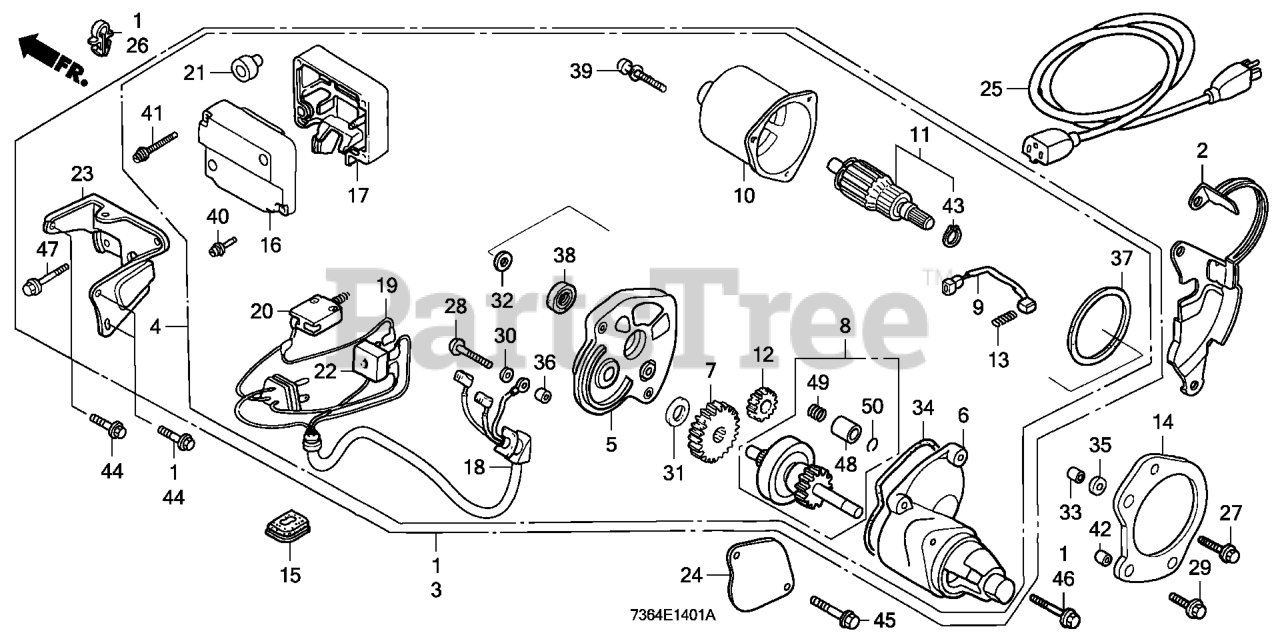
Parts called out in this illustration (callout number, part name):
2	PLATE, SIDE (A.C. SEL) Use from Engine SN 2056820.
3	MOTOR ASSY., STARTER (A.C.) Use from Engine SN 2056820.
4	MOTOR ASSY., STARTER (A.C.) Use from Engine SN 2056820.
5	HOUSING, CENTER Use from Engine SN 2056820.
6	HOUSING, PINION Use from Engine SN 2056820.
7	GEAR, REDUCTION Use up to Engine SN 2056819.
8	CLUTCH Use from Engine SN 2056820.
9	BRUSH Use from Engine SN 2056820.
10	YOKE Use from Engine SN 2056820.
11	ARMATURE Use from Engine SN 2056820.
12	GEAR, DRIVE Use up to Engine SN 2056819.
13	SPRING, BRUSH RETURN Use from Engine SN 2056820.
14	BRACKET, STARTER MOTOR
16	COVER Use from Engine SN 2056820.
17	CASE Use from Engine SN 2056820.
18	WIRE Use from Engine SN 2056820.
19	SUB-WIRE Use up to Engine SN 2056819.
20	SWITCH, STARTER (Honda Code 2299584). (A.C. 380V-16A)
20	SWITCH, STARTER (Honda Code 2773141). (A.C. 250V-16A)
21	CAP Use up to Engine SN 2056819.
22	DIODE Use up to Engine SN 2056819.
23	BRACKET, SWITCH BOX Use up to Engine SN 2056819.
26	HOLDER, STOP SWITCH WIRE Use up to Engine SN 2056819.
28	SCREW, TRUSS (4X30) Use from Engine SN 2056820.
30	WASHER, STAR (4MM) Use from Engine SN 2056820.
31	WASHER (A) Use from Engine SN 2056820.
32	WASHER (B) Use from Engine SN 2056820.
34	O-RING Use from Engine SN 2056820.
36	COLLAR Use from Engine SN 2056820.
37	GASKET Use from Engine SN 2056820.
38	OIL SEAL Use up to Engine SN 2056819.
39	SCREW-WASHER (5X30) Use up to Engine SN 2056819.
40	SCREW-WASHER (4X20)
41	SCREW-WASHER (4X30)
42	PIN A, DOWEL (8X14)
43	CIRCLIP (OUTER) (12MM) Use up to Engine SN 2056819.
44	BOLT, FLANGE (6X10)
46	BOLT, FLANGE (6X20)
47	BOLT, FLANGE (6X40)
48	STOPPER, PINION Use from Engine SN 2056820.
49	SPRING, COIL
50	RING, RETAINING Use from Engine SN 2056820.
